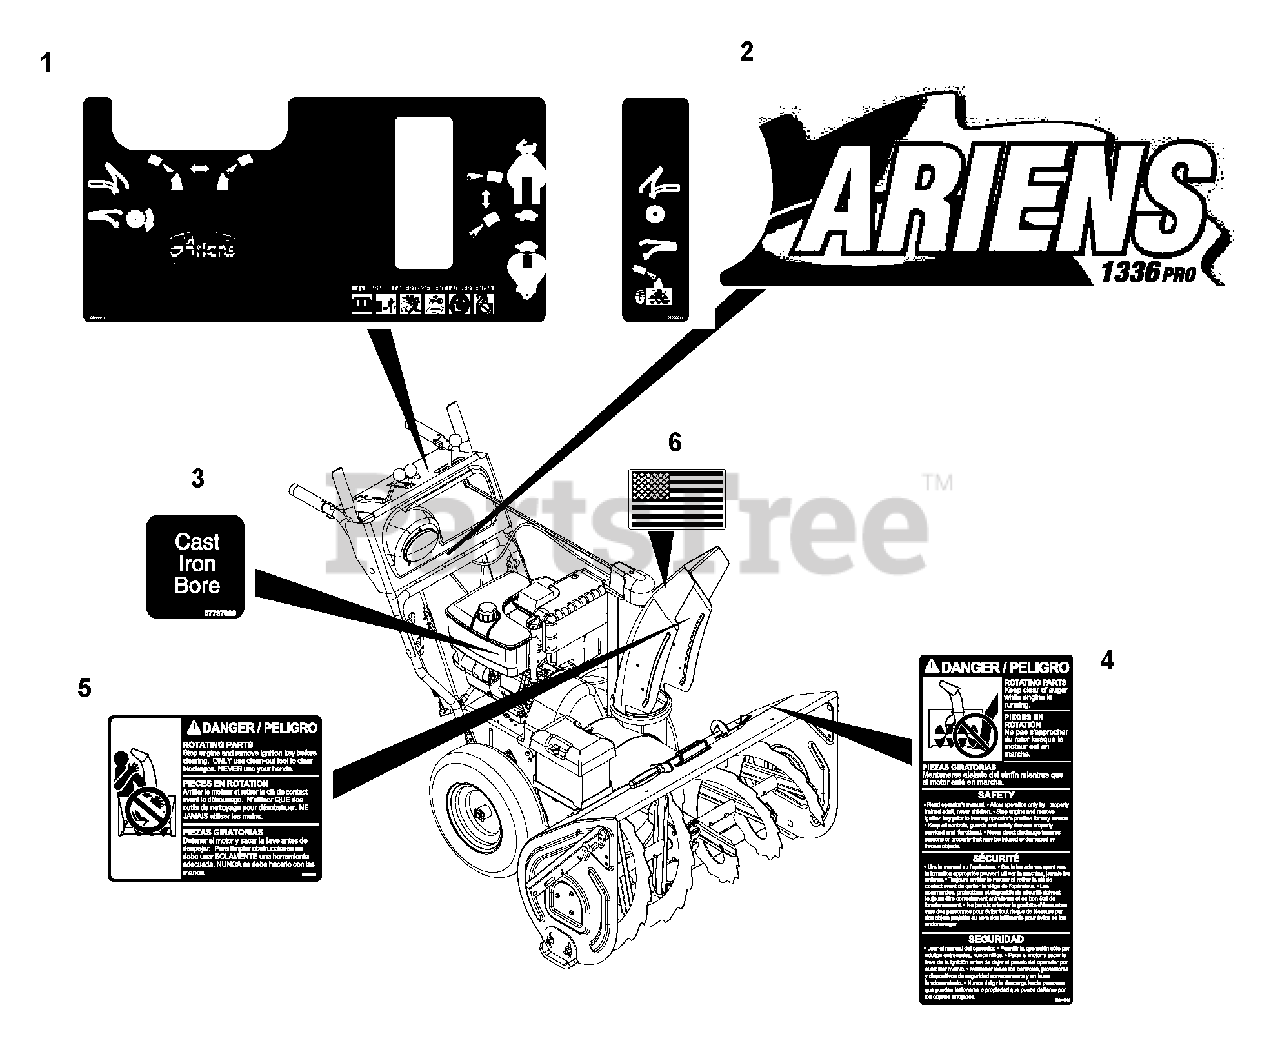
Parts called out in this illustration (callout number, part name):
1	DECAL, CONTROL
2	DECAL, FRONT DASH-926LE
3	DECAL - CAST IRON BORE
4	DECAL, DANGER
5	DECAL, DANGER - ROT. PARTS
6	DECAL, AMERICAN FLAG
